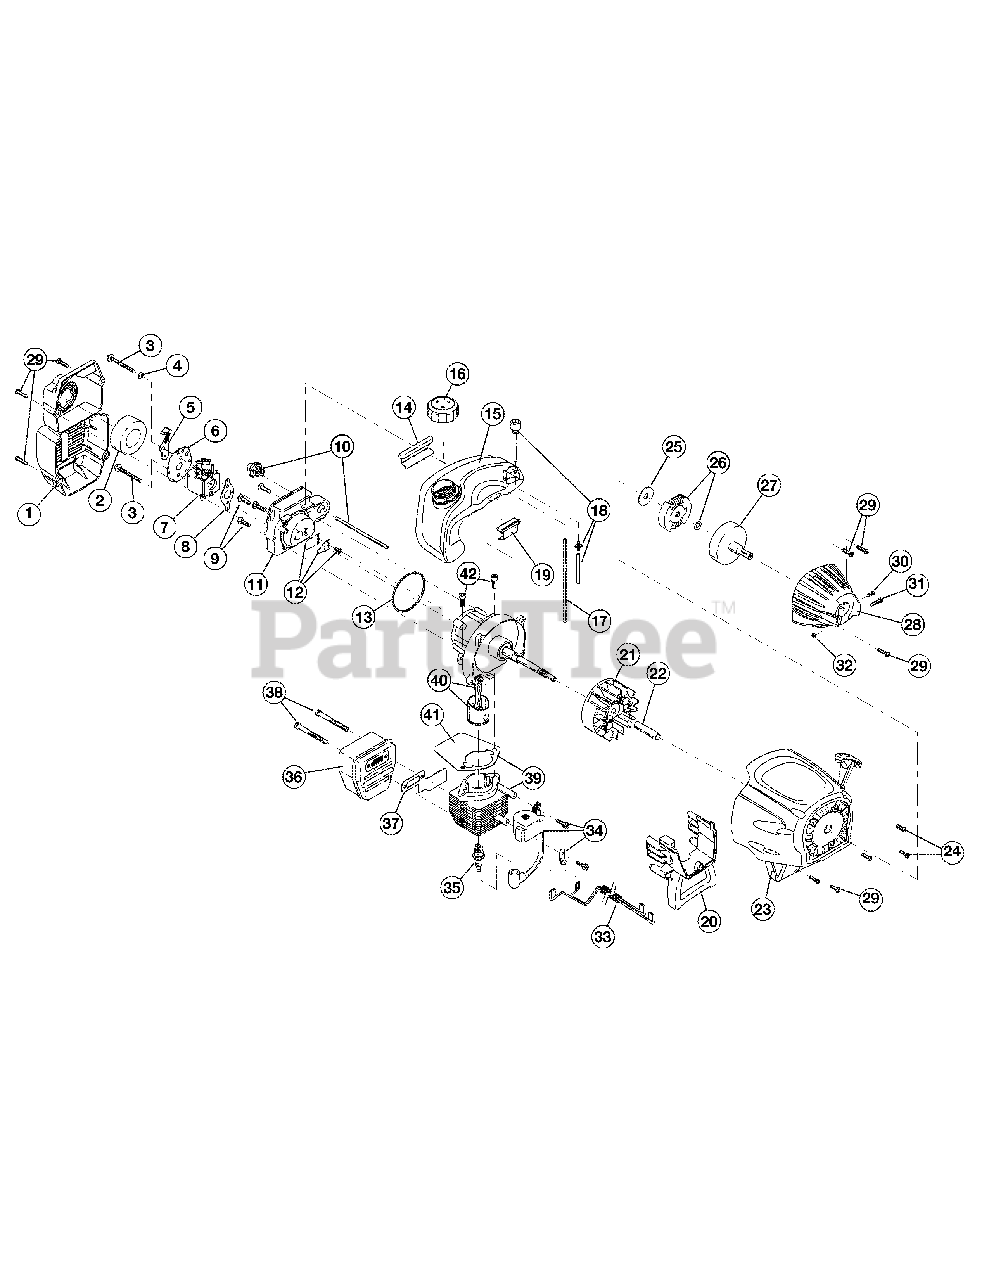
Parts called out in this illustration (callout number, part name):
1	Air Cleaner Cover Assembly
2	Air Cleaner Filter
3	Carburetor Mounting Screw Assembly
4	Wavey Washer
5	Choke Lever Assembly
6	Choke Plate Assembly
7	Carburetor Assembly
8	Carburetor Gasket
9	Carb Mount Screw
10	Primer & Hose Assembly
11	Carb Mount Assembly
12	Reed Assembly
13	Carburetor O-Ring
14	Rear Mounting Pad
15	Fuel Tank Assembly
16	Fuel Cap Assembly
17	Fuel Return Line
18	Fuel Line Assembly
19	Front Mounting Pad
20	Shroud Extension & Stand
21	Flywheel Assembly
23	Starter Housing Assembly
24	Housing Screw
25	Clutch Washer
26	Clutch Rotor Assembly
27	Clutch Drum Assembly
28	Clutch Cover Assembly
30	Anti-Rotation Screw
31	Clamping Screw
32	Clamping Nut
33	Wire Leads and Sleeve
34	Module Assembly
36	Muffler Assembly
37	Exhaust Gasket
38	Muffler Mounting Bolts
39	Cylinder Assembly
40	Piston and Rod Assembly
41	Cylinder Gasket
42	Cylinder Bolt
